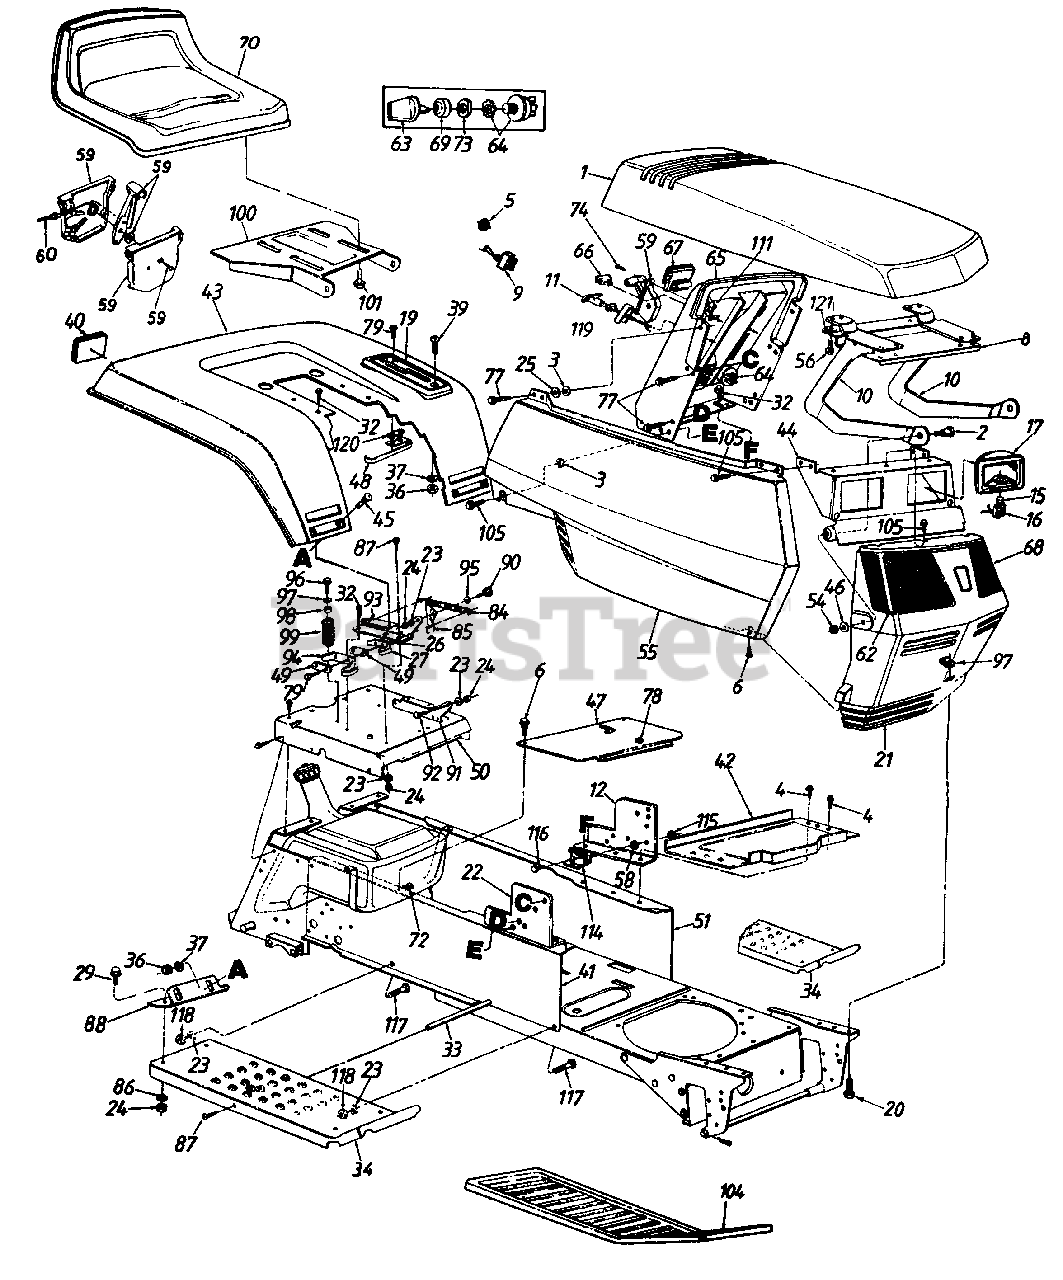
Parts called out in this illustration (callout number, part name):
2	Shld. Bolt .437" Dia. x .35"
3	Bolt Retainer 1/4" I.D.
4	Hex AB-Tap Scr. 1/4 x .62" Lg.
5	Hex Nut 1/2-27 Thd.
6	Truss Mach. B-Tap Scr. #10 x .5" Lg.
16	Twist Lock - Lamp Socket
17	Headlight Housing
19	Speed Control Index Brkt.
20	Hex Bolt 5/16-18 x .75" Lg.
21	Grille
24	Hex Nut 5/16-18 Thd. (Gr. 5)
25	Fl-Wash. 1/4" I.D. x .93" O.D.
26	Insulator Boss Plate
27	Seat Spring Switch
29	Hex Bolt 5/16-18 x 1.0" Lg.
32	Hex Wash. Hd. AB-Tap Scr. 5/16 x .75" Lg.
37	L-Wash. 1/4" I.D.
39	Truss Mach. Scr. 1/4-20 x 1.0" Lg.
40	Reflector
46	Fl-Wash .328" I.D. x .68" O.D.
49	Insulator Plate
50	Seat Plate
55	Side Panel Ass'y.- R.H.
56	Hex Wash. Hd. B-Tap Scr. 1/4 x .62" Lg.
58	Ext. L-Wash. 1/4" I.D.
59	Throttle Control Box Ass'y.
60	Throttle Control Wire 35" Lg.
62	Lens - R.H.
63	Ignition Key
64	Ignition Switch
65	Dash Panel
66	Light Switch
67	Ammeter
68	Lens - L.H.
69	Ignition Switch Cap
70	Seat Ass'y.
72	Speed Nut #10Z
73	Ignition Switch Nut
74	Truss Mach. AB-Tap Scr. #10 x .5" Lg.
77	Hex Wash. Hd. Tap Scr. 1/4 x .75" Lg.
78	Snap Bushing
79	Hex Wash. Hd. AB-Tap Scr. #8 x .50" Lg.
84	Ext. Spring 5.31" Lg.
85	Seat Lift Brkt.
86	Bell-Wash .345" I.D. x .88" O.D.
87	Truss Machine Scr. 5/16-18 x .75" Lg.
95	Spr.-Wash .445" I.D.
96	Hex Wash. Hd. Tap Scr. 5/16-18 x .75" Lg.
97	U-Nut 5/16-18 Thd.
98	Bushing
99	Compression Spring
101	Hex Tap Scr. 3/8-16 x .62"
104	Foot Pad
105	Hex Tap Scr. 1/4-20 x .5" Lg.
111	Speed Nut 1/4-20 Thd.
114	Solenoid
115	Hex Sems Nut 1/4-20 Thd.
116	Hex Bolt 1/4-20 x .5" Lg.
117	Rib Neck Bolt 5/16-24 x .75" Lg.
118	Hex Nut 5/16-24 Thd.
119	Retainer Clip
120	lnsulator Nut Plate
